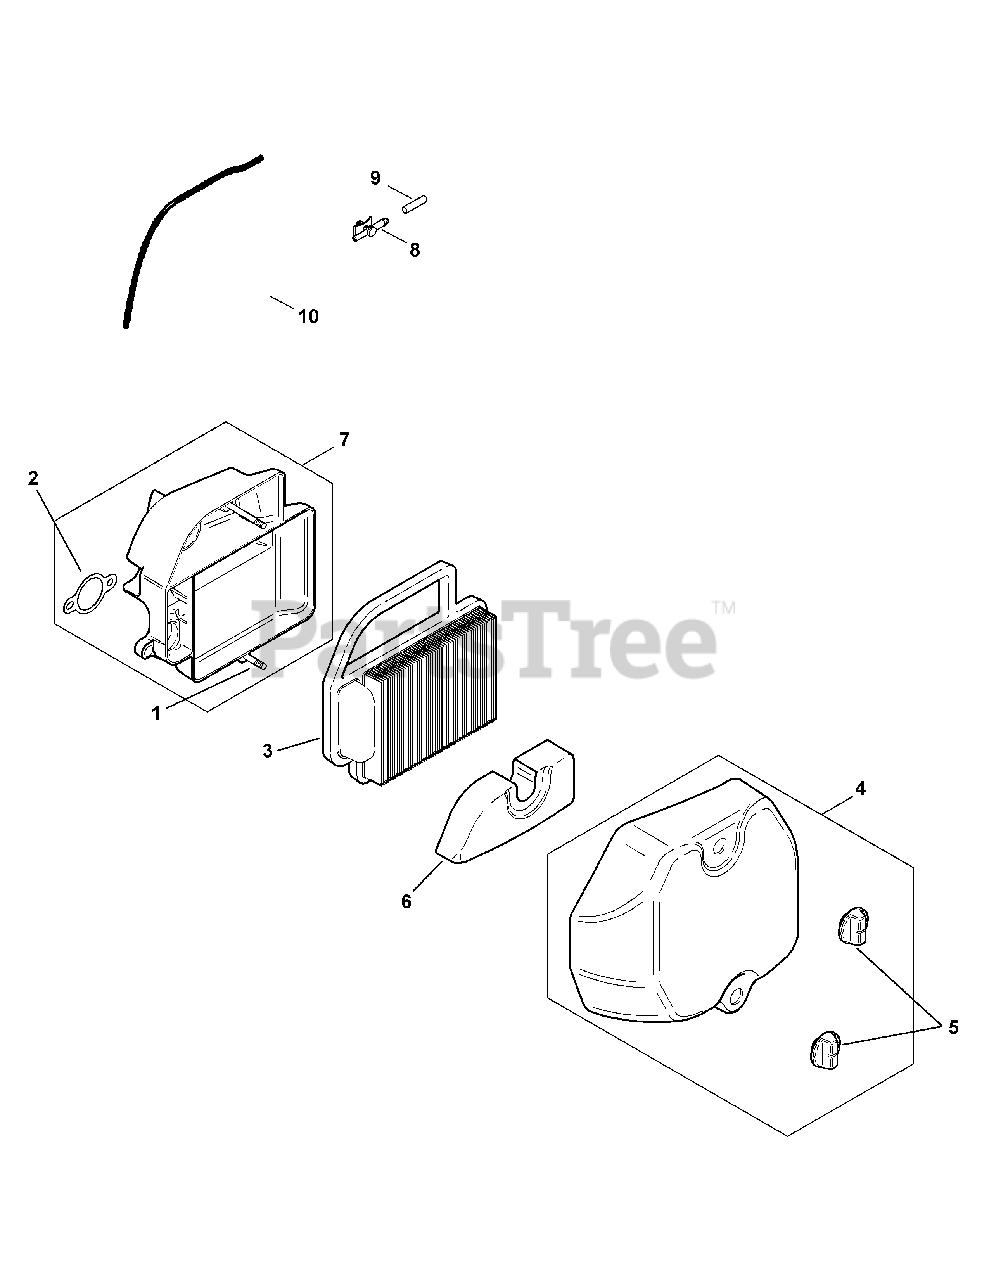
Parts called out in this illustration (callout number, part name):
1	Air Cleaner Base Stud
2	Air Cleaner Base Gasket
3	Air Cleaner & Pre-Cleaner Element
4	Air Cleaner Cover Kit
6	Pre-Cleaner Element (Dry)
7	Air Cleaner Base Kit
8	Evaporative Connector
10	Hose, Evaporative, 20"
